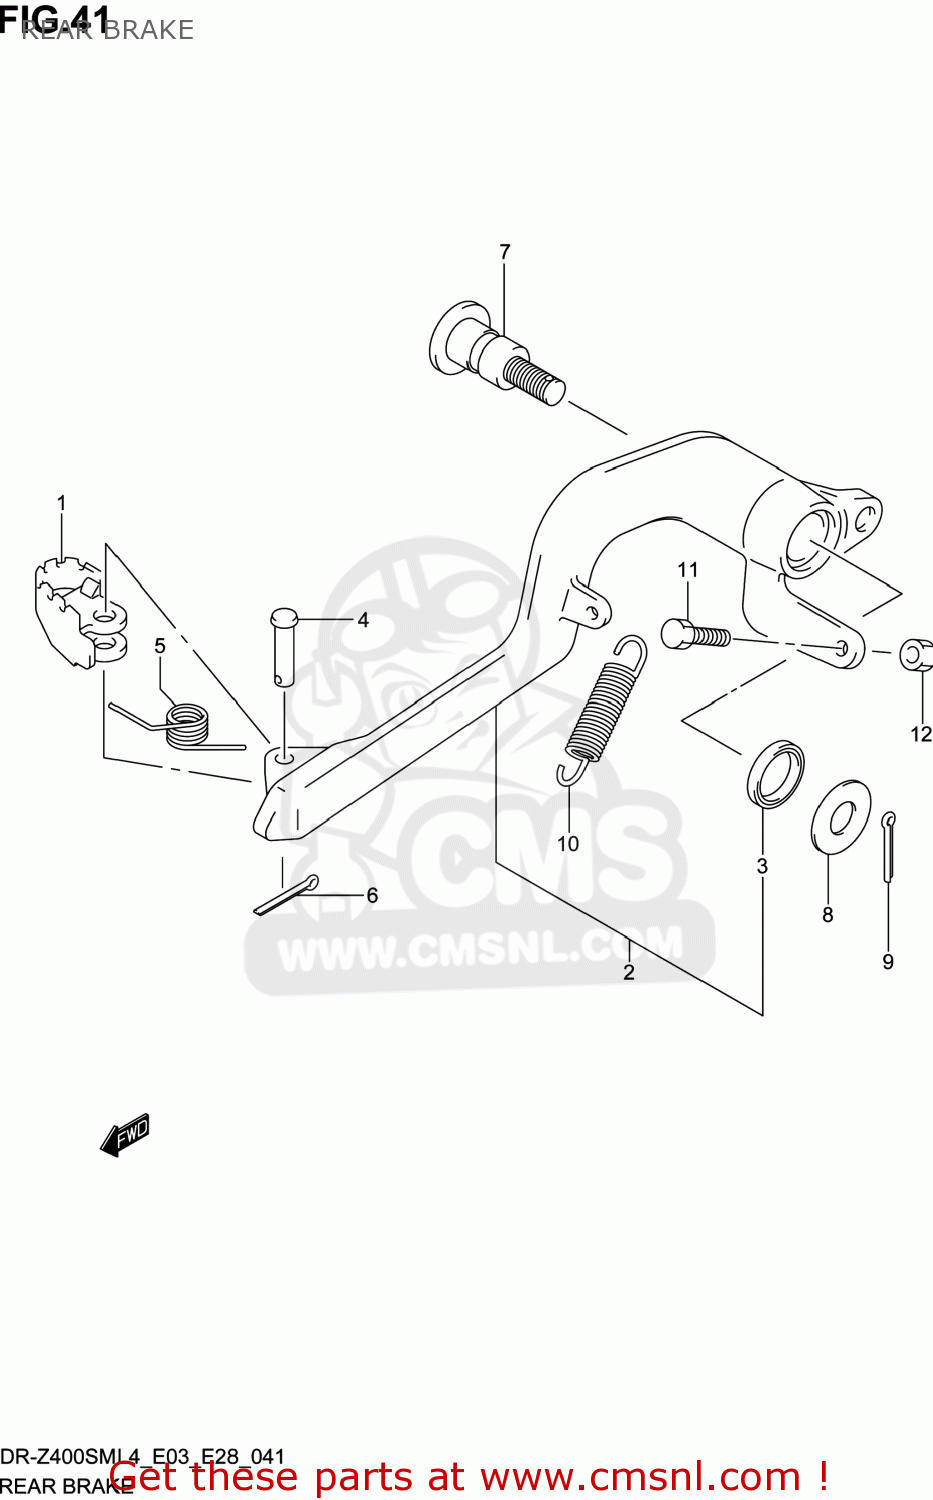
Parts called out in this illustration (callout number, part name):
1	PEDAL,BRAKE
2	ARM,BRAKE PEDAL
3	SEAL,OIL(15X21X3)
4	PIN(6X23.5)
5	SPRING
6	PIN
7	SHAFT,BRAKE PEDAL
8	WASHER
9	PIN
10	SPRING
11	BOLT(6X30)
12	NUT
